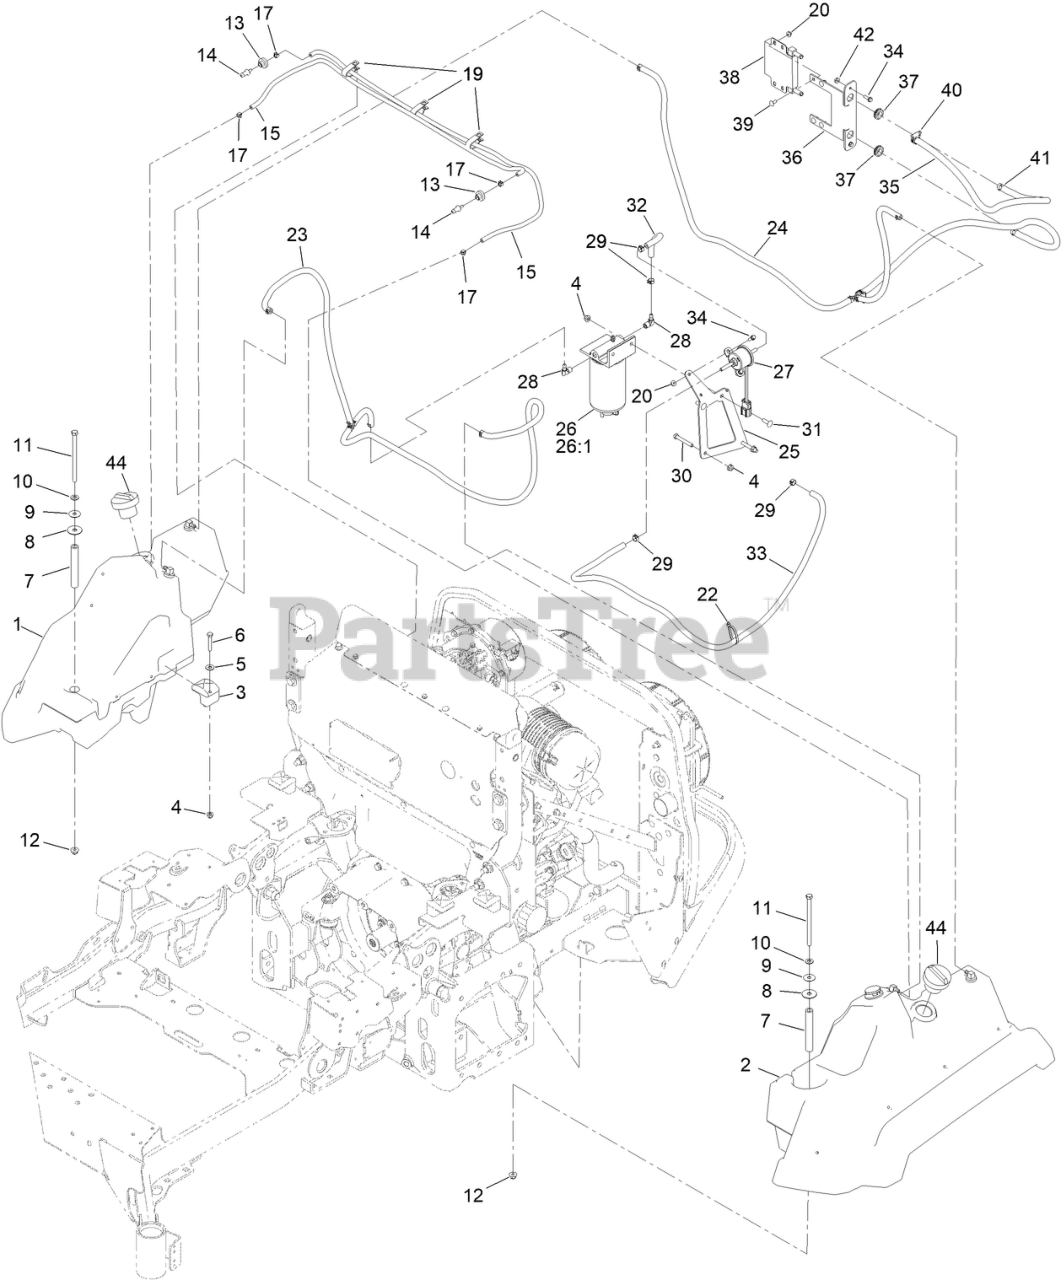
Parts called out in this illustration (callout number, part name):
1	RH FUEL TANK ASM
2	LH FUEL TANK ASM
4	NUT-HF, NI
5	WASHER-FLAT
6	SCREW-HH
7	TUBE-SPACER
8	WASHER-RUBBER
9	WASHER-PLAIN
10	WASHER-FLAT
11	SCREW-HH
12	NUT-HF, NI
13	BUSHING
14	FITTING-ORIFICE, STRAIGHT
15	HOSE-VENT, TANK
17	CLAMP-HOSE
19	CLAMP-HOSE
20	NUT-HF
22	TIE-CABLE
23	FUEL SUCTION LINE ASM
24	HOSE ASM-FUEL, TEE
25	BRKT-FUEL FILTER
26	SEPARATOR FILTER ASM
26:1	FILTER-FUEL/WATER SEPARATOR
27	PUMP-FUEL, ELECTRIC
28	FITTING-HYD, 90
29	CLAMP-HOSE
30	SCREW-HH
31	SCREW-CARR
32	HOSE-FUEL
33	HOSE-FUEL
34	SCREW-HWH
35	HOSE-FUEL
36	MOUNT-COOLER, FUEL
37	GROMMET
38	COOLER-OIL
39	SCREW-CARR
40	CLAMP-HOSE
41	CLAMP-HOSE
42	NUT-HF
44	CAP-FUEL, DIESEL (ULTRA LOW SULFUR)
